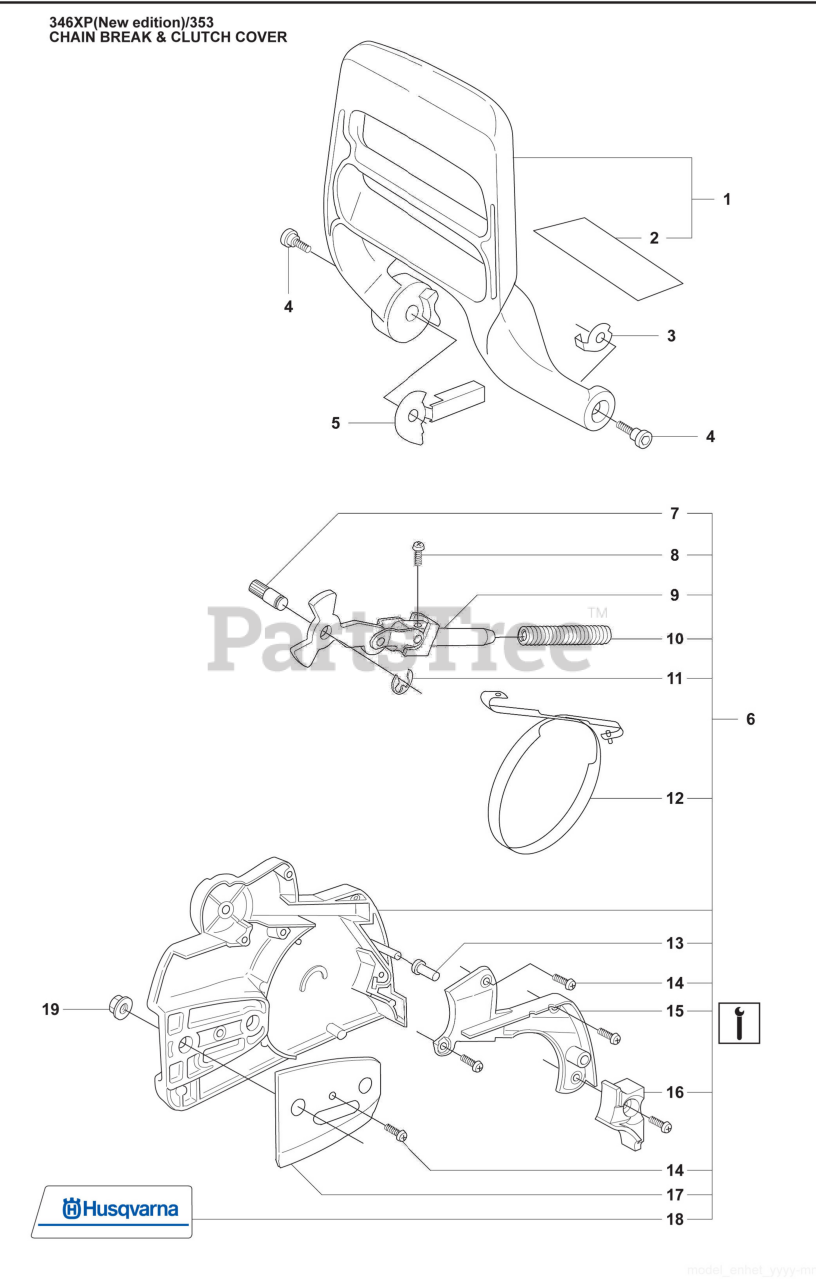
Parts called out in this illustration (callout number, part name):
1	Chain Brake Handle
2	Protector
6	Chain Brake
6	Chain Break, Silver
11	Bar Retainer
12	Brake Band
19	Flange Hex Nut, M8
